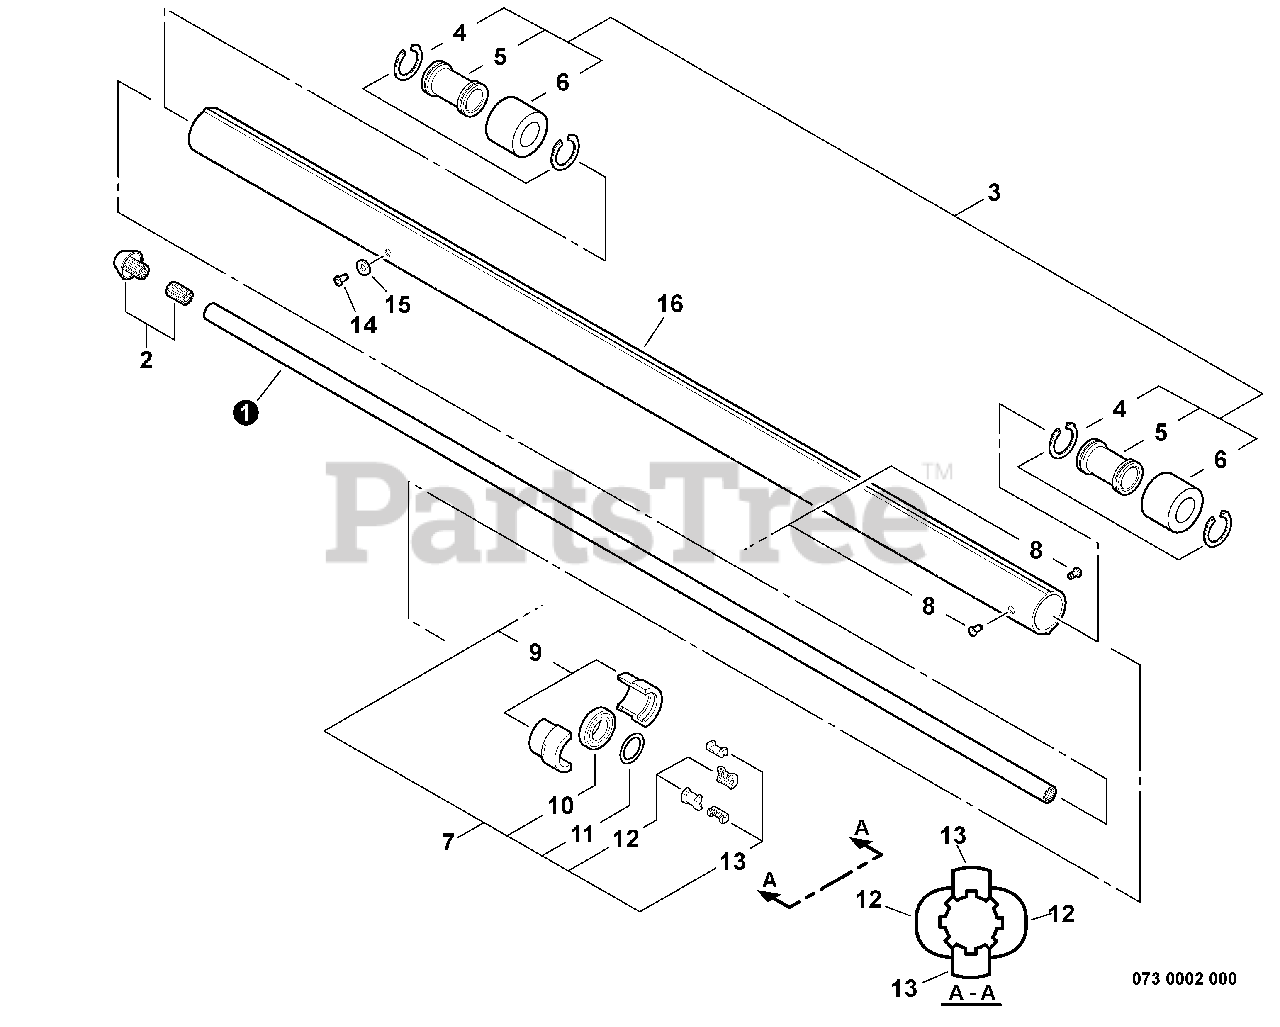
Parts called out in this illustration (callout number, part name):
1	DRIVESHAFT - UPPER
2	ADAPTER, DRIVESHAFT - UPPER
3	DRIVESHAFT GUIDE ASSY
4	RING, RETAINING
5	GUIDE, DRIVESHAFT
6	PAD, FOAM
7	BEARING HOLDER KIT
9	BEARING HOLDER KIT
10	BEARING, BALL - 6002
11	WASHER - SPRING
12	HOLDER, INNER BEARING - LARGE
13	HOLDER, INNER BEARING - SMALL
15	WASHER - 5
16	PIPE, MAIN - UPPER -- BLACK
